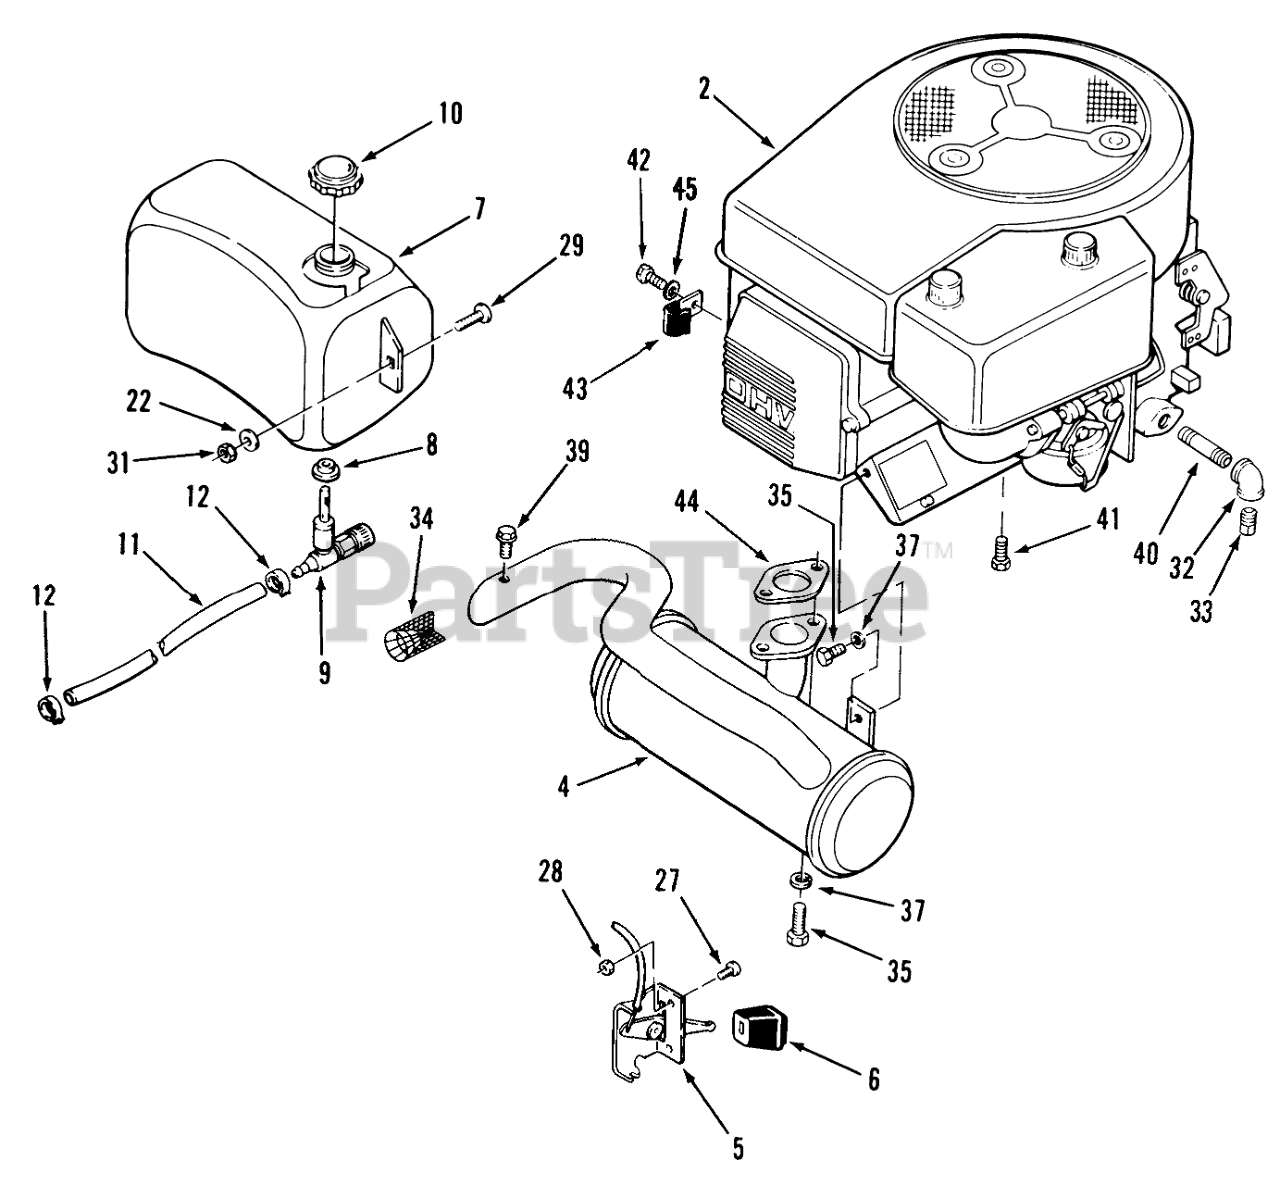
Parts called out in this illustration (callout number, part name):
2	Engine-12HP TORO Power Plus Model No. E125V Type N/10964B
4	MUFFLER-EXHAUST
5	CONTROL-THROTTLE
6	KNOB-CONTROL
7	Fuel Tank Assembly (Incl. Ref. #8 & 9)
8	BUSHING
9	VALVE-FUEL
10	CAP GAS
11	Line-Fuel
12	CLAMP-HOSE
22	WASHER-PLAIN
27	SCREW #10X.62 PHCR
28	Nut
29	BOLT-CARR
31	NUT-LOCK, NI
32	ELBOW 3/8 90 DEG
33	Plug-Pipe
34	Arrester-Spark
35	HHCS M8X1.25X20
37	WASHER-LOCK
39	BOLT-HEX S.T. #8X1/2
40	Pipe
41	Bolt
42	SCREW
43	J-CLIP
44	GASKET-EXHAUST
45	WASHER-LOCK
